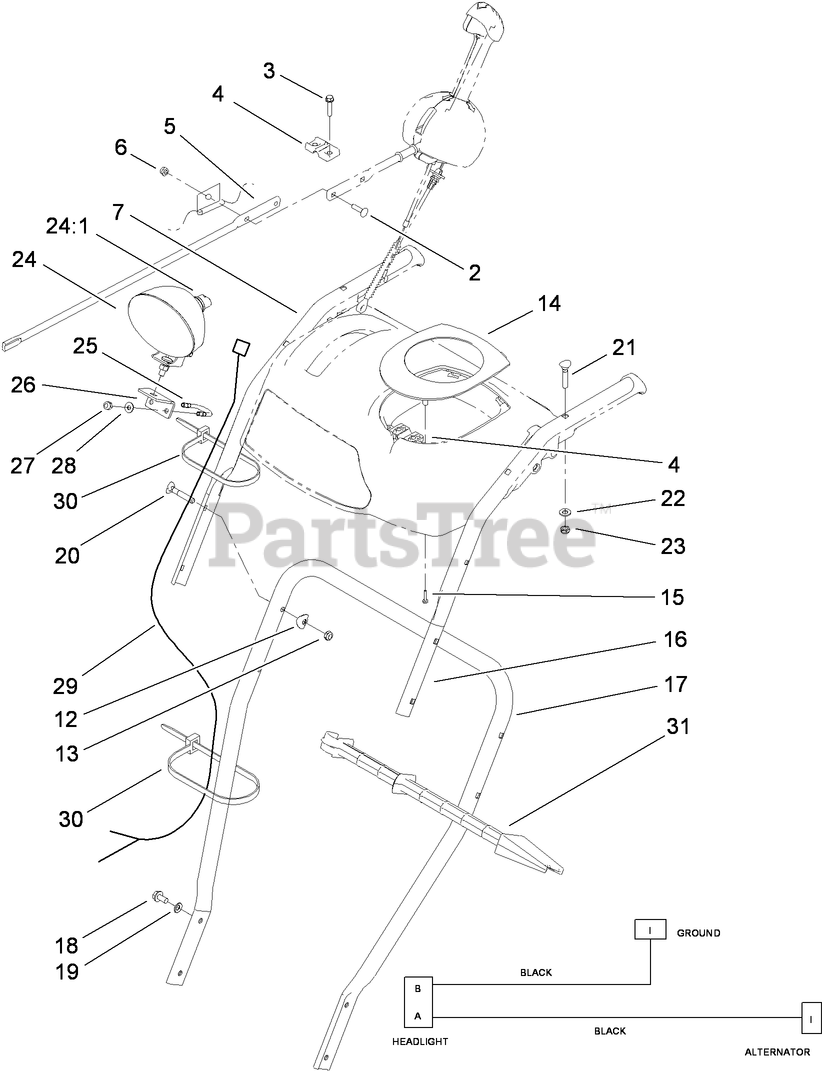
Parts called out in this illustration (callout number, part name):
2	SCREW-CARR
3	SCREW-PLASTITE
4	SUPPORT-ROD
5	ROD-CHUTE, FRONT
6	NUT-LOCK, NI
7	HANDLE-UPPER, RH
12	WASHER
13	NUT-LOCK, NI
14	COVER-PANEL, CONTROL
15	SCREW-PPH
16	HANDLE-UPPER, LH
17	HANDLE-LOWER
18	SCREW-HWHTF
19	WASHER-BELLEVILLE
20	SCREW-HANDLE
21	SCREW-HANDLE
22	WASHER-FLAT
23	NUT-LOCK, NI
24	HEADLAMP ASM
24:1	LAMP-12 VOLT
25	CLAMP
26	BRACKET-LIGHT
27	NUT-LOCK, NI
28	WASHER-FLAT
29	HARNESS-WIRE
30	TIE-CABLE
31	STICK-CLEANOUT
